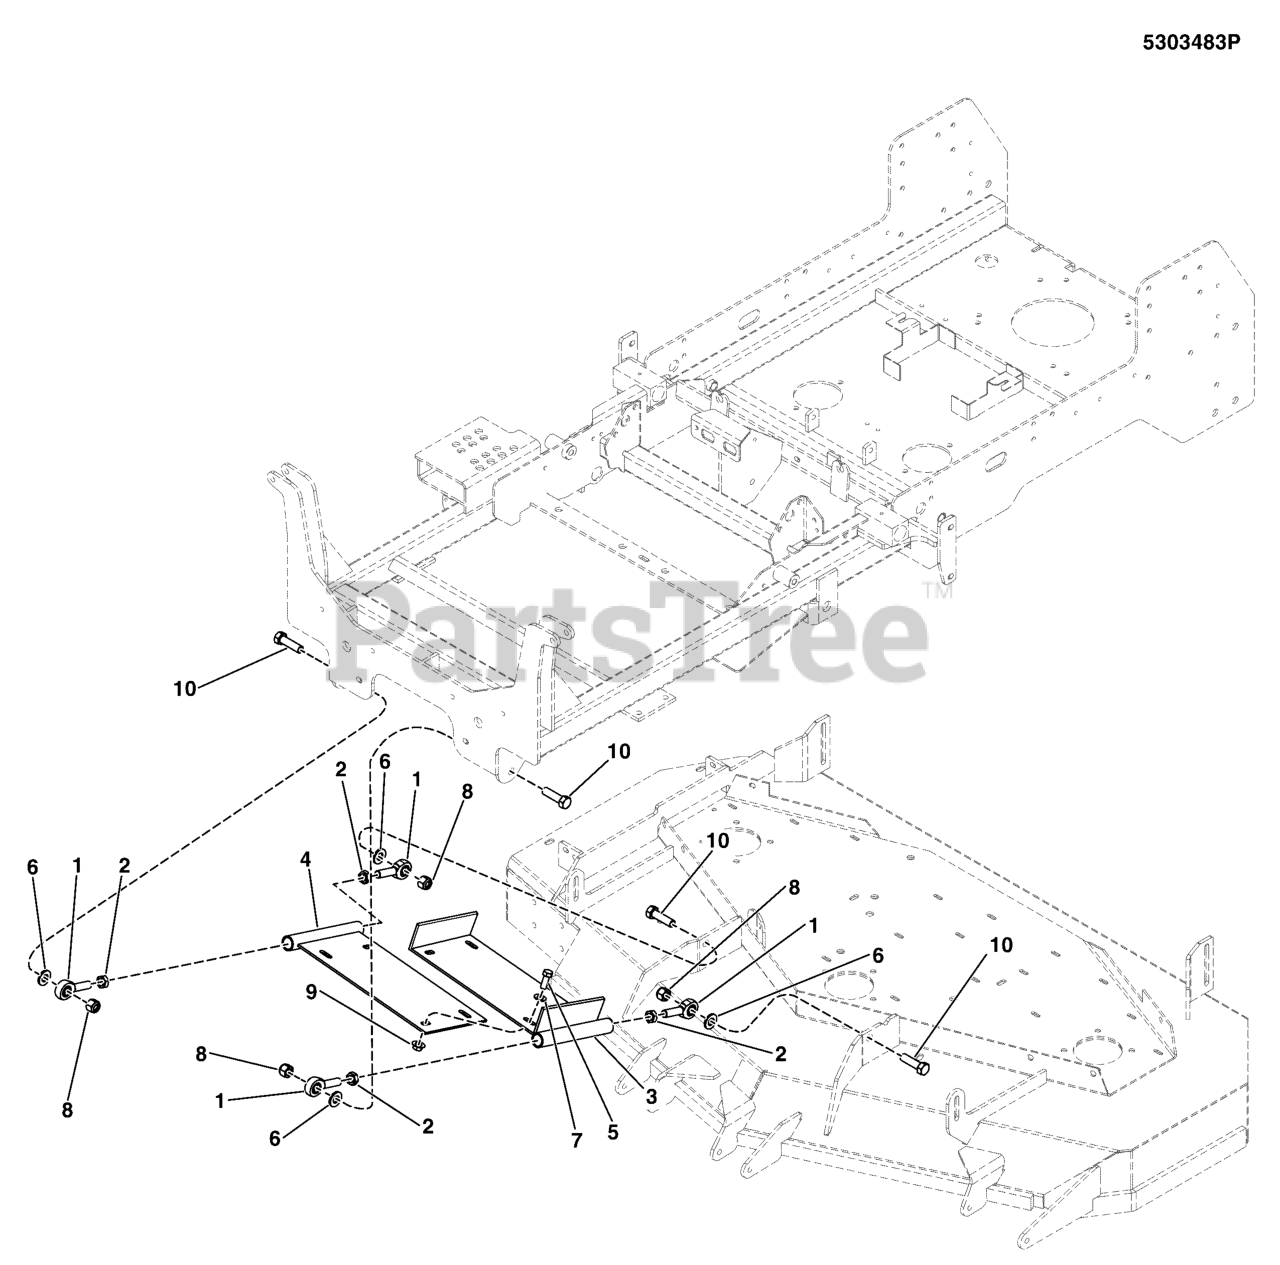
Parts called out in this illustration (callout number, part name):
1	BALL JOINT, 1/2-20, MALE
2	NUT, 1/2-20 HEX JAM
3	WELD, DECK STABILIZER, LH, IS2500 - BLK
4	WELD, DECK STABILIZER, RH, IS2500 - BLK
5	BOLT, 3/8-16 X 1" GD5 CZ
6	WASHER, 1/2" GD9 YZ
7	WASHER, 3/8 SAE
8	NUT, Hex, Nylon Lock, 1/2-20
9	NUT, 3/8-16 HEX LG. SERR FLG
10	BOLT, 1/2-20 X 1-3/4" GD8 CZ
